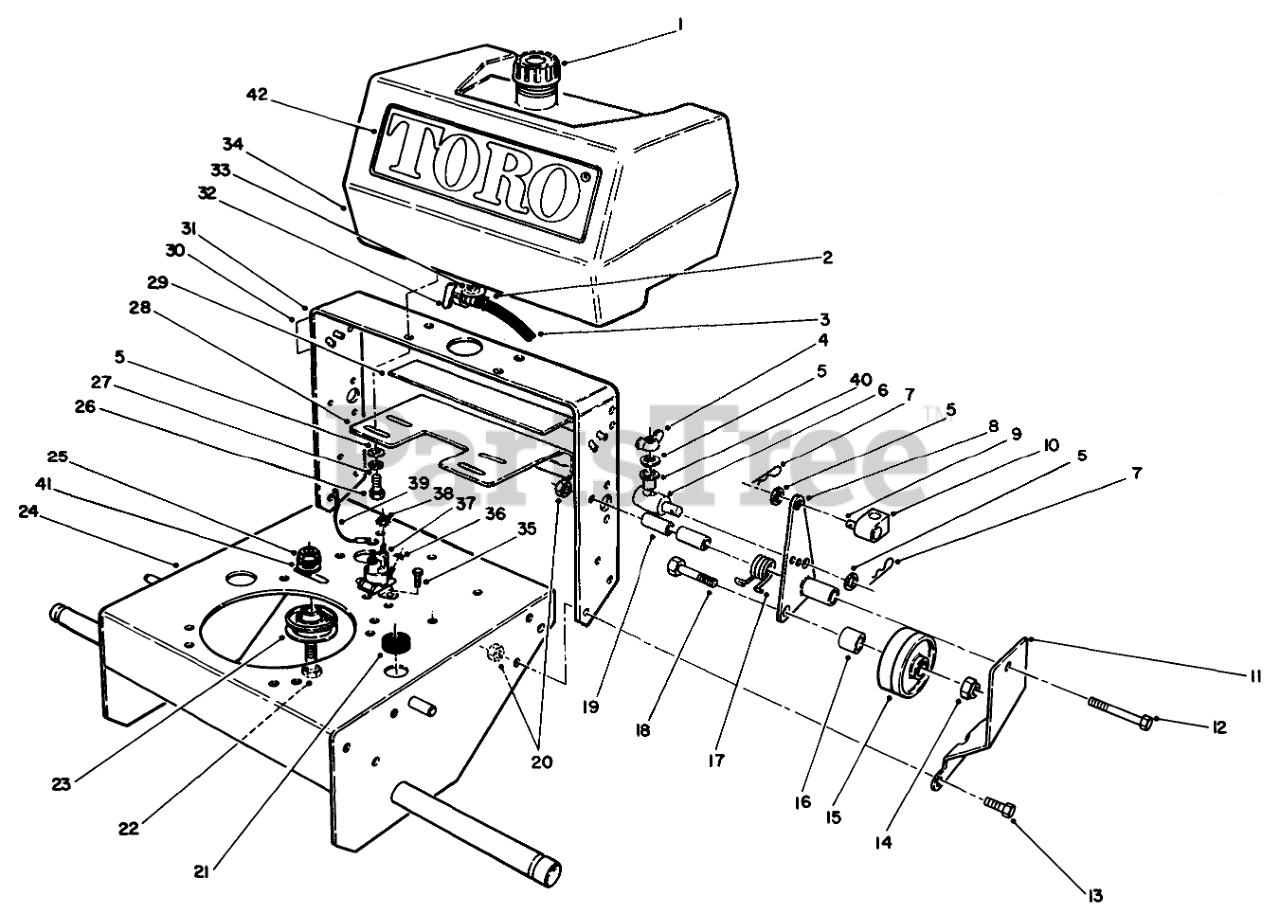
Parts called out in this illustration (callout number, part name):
1	GAS CAP ASM
2	CLAMP-HOSE
3	HOSE-FUEL
4	NUT-WING
5	WASHER-PLAIN
6	Fitting-Rod
7	PIN-COTTER
8	BRACKET-Idler, LH
9	PIN-CLEVIS
10	FITTING-ROD
11	Bracket-LH
12	SCREW-HH
13	SCREW-HH
14	NUT-LOCK, NI
15	IdlerWheel
16	WHEEL IDLER SPACER
17	SPRING-TORSION, LH
18	SCREW-LEVELER
19	SPACER-PIVOT, IDLER
20	NUT-LOCK, NI
21	GROMMET
22	SCREW-HH
23	PULLEY-IDLER
24	FRAME
25	NUT-HF
26	SCREW-HH
27	WASHER-LOCK
28	Plate
29	DECAL-GROUND SPEED
30	DECAL-FUEL SHUT OFF
31	Frame Rear
32	VALVE-FUEL
33	O-RING
34	FUEL TANK
35	SCREW
36	NUT-KEPS
37	Solenoid
38	NUT-KEPS
39	WIRE-SOLENOID/STARTER
40	BUSHING-NYLON
41	WASHER-FLAT
42	Decal-Toro
